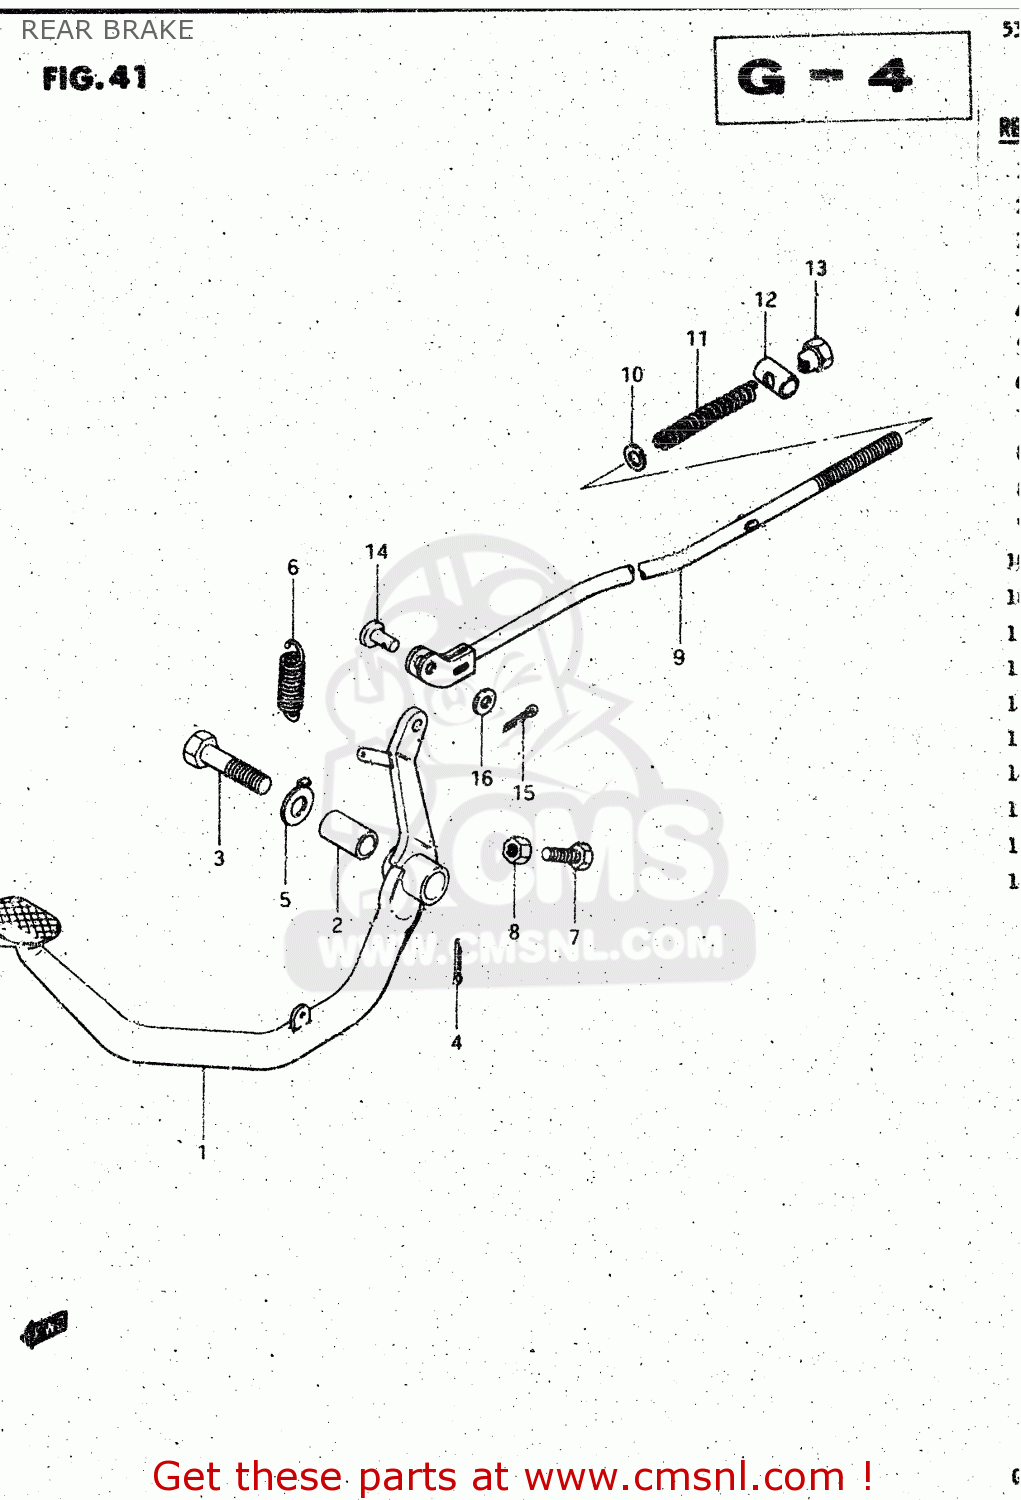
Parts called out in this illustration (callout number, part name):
1	PEDAL,BRAKE
2	SPACER,BRAKE PEDAL BOSS
3	BOLT 10X52
4	PIN 20X20
5	WASHER
6	SPRING
7	BOLT(6X23)
8	NUT 6MM
9	ROD ASSY,RR BRAKE
10	WASHER
11	SPRING
12	PIN(11X18)
13	NUT
14	PIN(L:13.5)
15	PIN 20X20
16	WASHER
